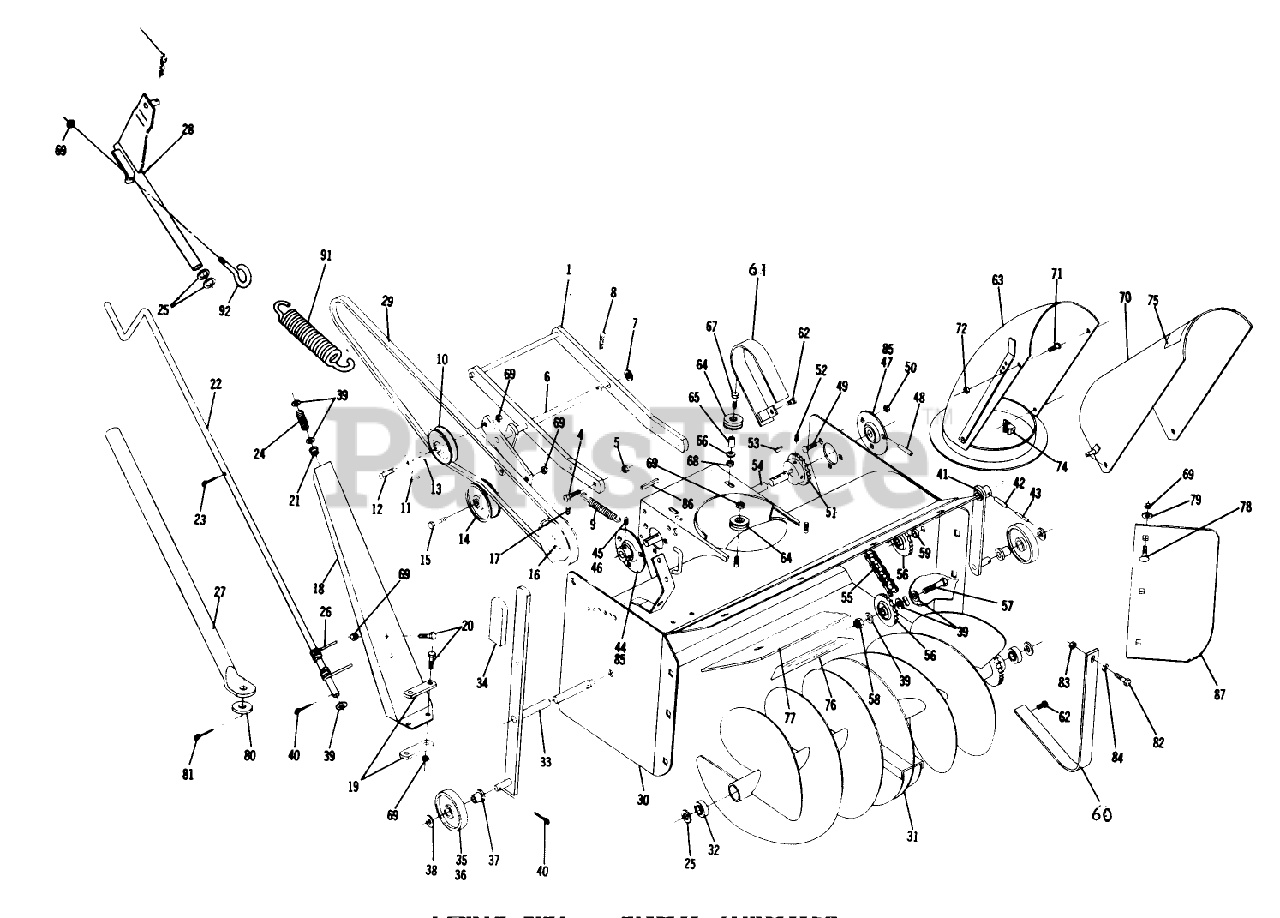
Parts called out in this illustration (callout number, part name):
1	Frame-Mounting
4	Bolt
5	Nut
6	ASSY IDLER ARM R
7	Washer
8	Hairpin
9	SPRING R
10	PULLEY-IDLER
11	Spacer
12	Bolt
13	SPACER
14	Idler Pulley
15	BOLT
16	Pulley
17	Set Screw
18	Crank Support
19	Bar-Reinforcing
20	Bolt
21	NYLINER BUSHING
22	Crank Assembly
23	Pop Rivet
24	SPRING-COMPRESSION
25	Washer
26	CABLE
27	Lift Tube
28	LIFT ROD ASM
29	V-BELT
30	Wrapper Assembly
31	Auger
32	BEARING-BALL
33	ASSY AUGER SHAFT R
34	GRIP
35	WHEEL BUSHING ASSY R
36	Wheel
37	Bushing
38	Washer
39	Washer
40	Pop Rivet
41	Wheel Support
42	ROLL PIN 1/4 X 1-1/4
43	PIN-SPIROL
44	Ball Bearing
45	Set Screw
46	SET SCREW
47	Ball Bearing
48	PIN-ROLL, SPIROL
49	Bolt
50	Nut
51	SPROCKET
52	SCREW-SET
53	Key
54	SHAFT
55	CHAIN
56	Idler Sprocket
57	H H C S
58	Eslok Nut
59	SPACER
60	Guard-Inner
61	Guard-Outer
62	SCREW
63	S/A SHROUD R
64	Roller
65	SPACER
67	Bolt
68	Nut
69	NUT
70	Deflector
71	MACH. SCREW
72	Nut
74	CLAMP
75	Decal-Caution
76	DECAL-WHEEL HORSE
77	Plate
78	Bolt
79	Washer
80	WASHER
81	Cotter Pin
82	H H C S
83	Nut 1/4-20
84	WASHER
85	FLANGE
86	KEY-STRAIGHT
87	Plate
88	H H C S
89	Nut
90	Decal-Safety
91	SPRING
92	EYEBOLT
